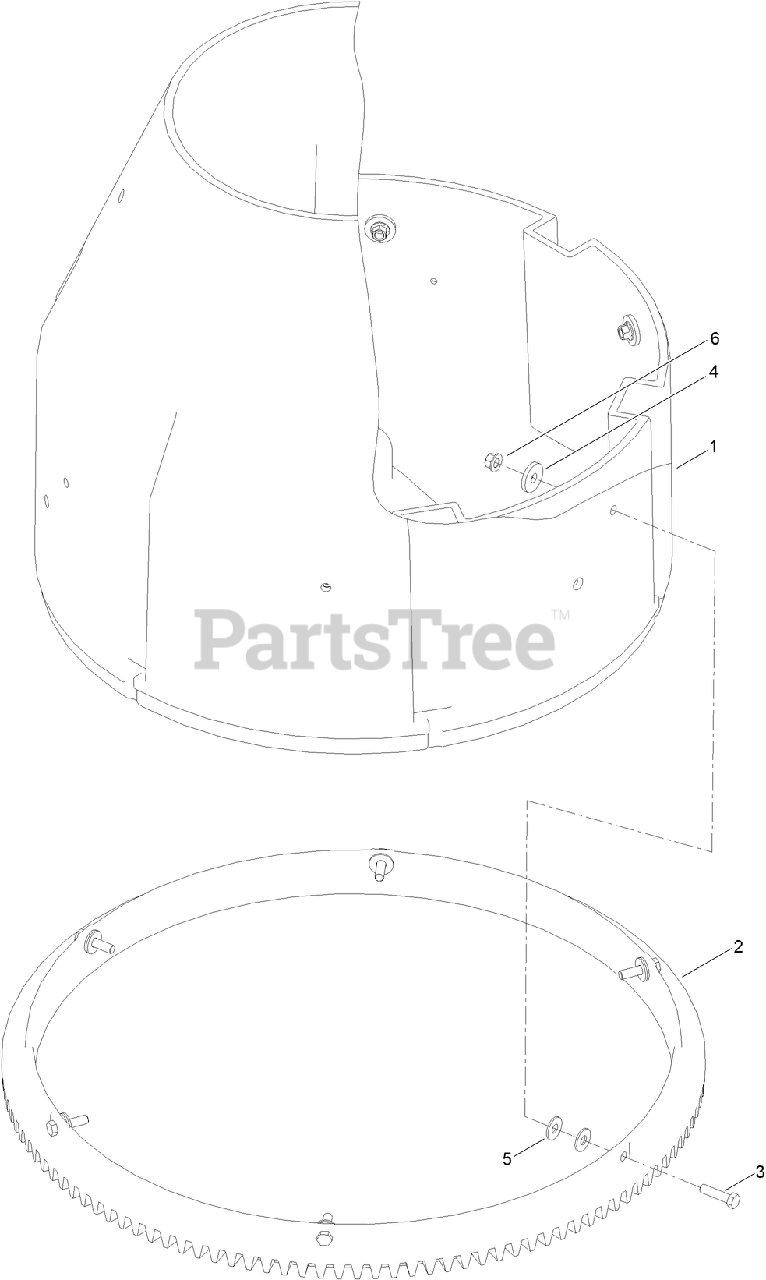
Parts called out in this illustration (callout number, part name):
1	DRUM
2	GEAR-RING
3	SCREW-HH
4	WASHER-FLAT
5	WASHER-FLAT
6	NUT-LOCK
